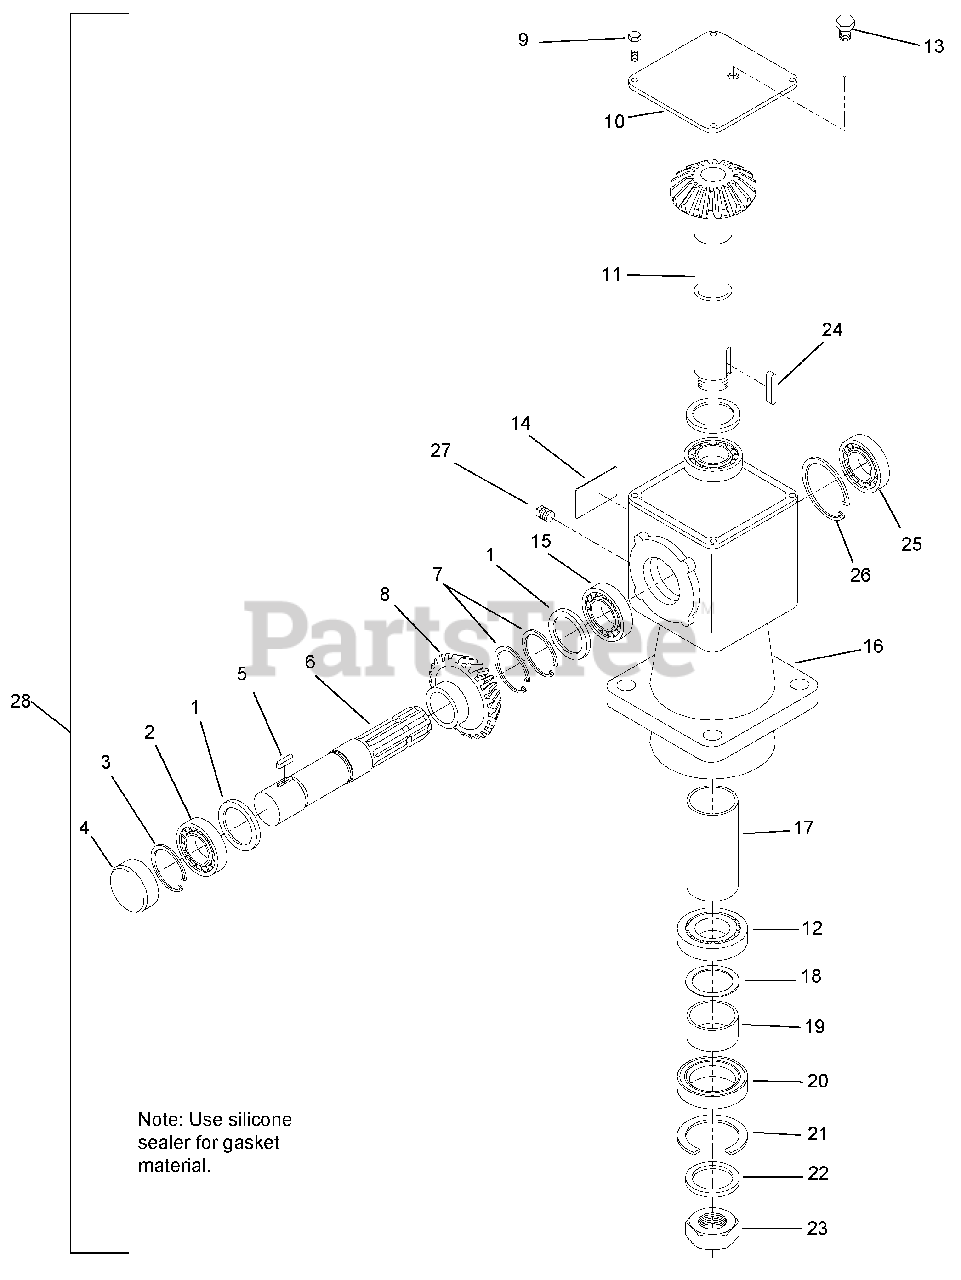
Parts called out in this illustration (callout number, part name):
1	Shim .3 mm
2	Flange, Bearing
3	Ring, Snap
5	Key, M10 x 8 x 30
7	Ring, Retaining
9	Cap Screw, M8 x 16 Grade 8
10	Plate, Top
13	Plug, Oil Level
14	Plate, Serial Number
17	Ring, Snap
21	Ring, Lock
22	Washer, Spring Outer Tooth
23	Nut, Hex M30 x 2
24	Key, 6 mm x 9 mm x 30 mm
26	Ring, Retaining
27	Plug, Oil Drain .38 MNPT
28	Gearbox Assembly, Series LF33A RA (Includes Items 1 – 27)
